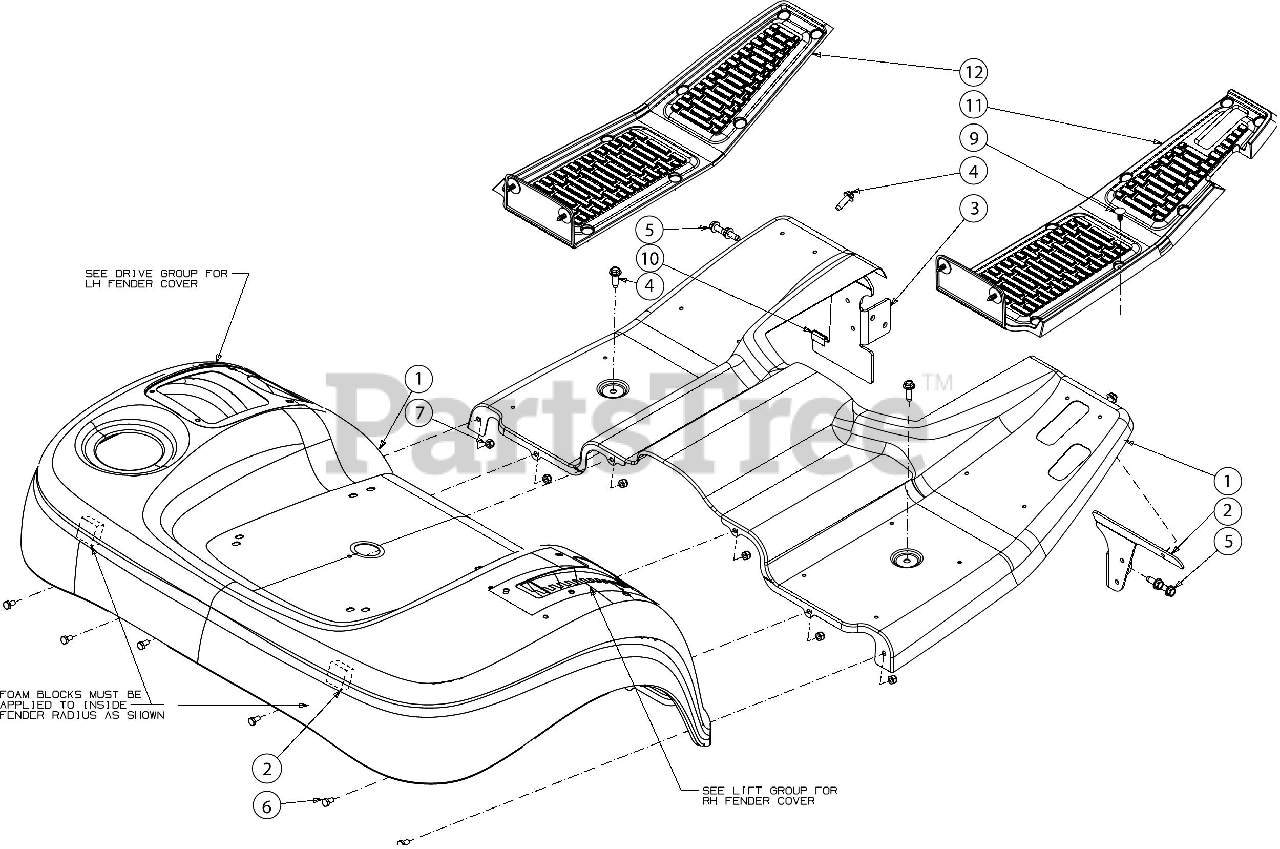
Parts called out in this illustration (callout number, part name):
1	RUNNING BOARD
2	RUNNING BOARD BRACKET (RH)
3	RUNNING BOARD BRACKET (LH)
4	SCREW 5/16-18 x 1.00
5	SCREW 5/16-18 x .750
6	SCREW 1/4-20X.5 GR5
7	NYLON LOCK NUT
8	FOAM-1.25SQ x .62T
9	RATCHET CLIP .250
11	FOOT PAD (RH)
12	FOOT PAD (LH)
